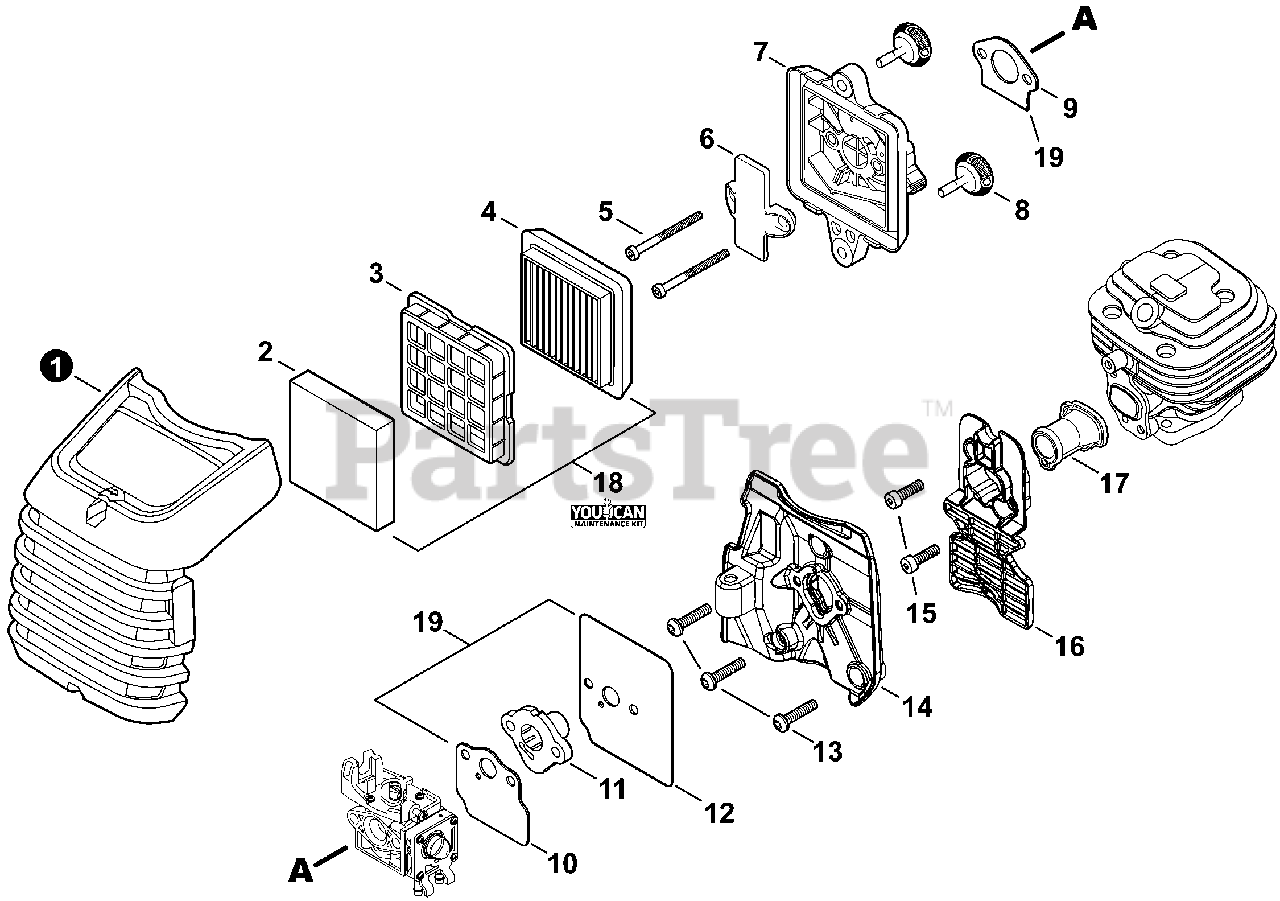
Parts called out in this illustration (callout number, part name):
1	COVER, AIR FILTER
2	PRE-FILTER, FOAM
3	RETAINER, PRE-FILTER
4	FILTER, AIR
5	BOLT, TORX 5×60
6	PLATE, PREVENT
7	CASE, AIR FILTER
8	THUMBSCREW
9	GASKET, INTAKE
10	GASKET, BOOT
11	BOOT, INTAKE
12	GASKET, INSULATOR PLATE
13	BOLT, TORX 5×16
14	PLATE, INSULATOR
15	SCREW 5×16
16	HOLDER, BELLOWS
17	BELLOWS, INTAKE
18	TUNE-UP KIT - YOUCANT
19	GASKET KIT
